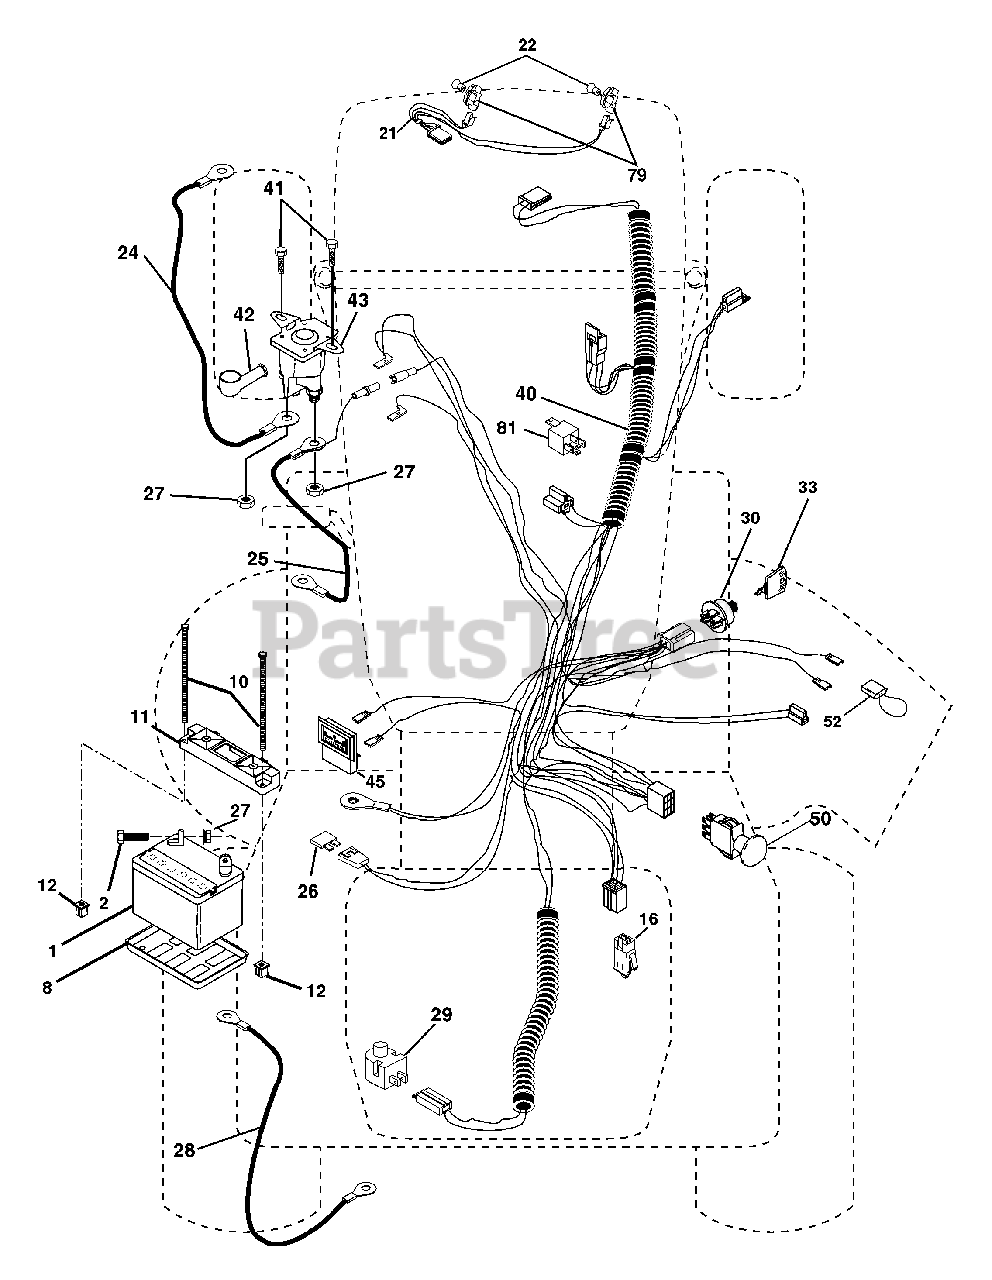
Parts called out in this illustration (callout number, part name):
1	Battery
2	Bolt Hex Head 1/4-20 x 3/4
8	Tray, Battery
10	Bolt Btr Frt 1/4-20 X 7.5 zinc
11	Holdown Battery Front Mount
12	Nut Push Nylon 1/4"
16	Switch Interlock Push-In
21	Harness Headlight
22	Bulb Light
24	Cable, Battery
25	Cable, Battery
26	Fuse
27	Nut Keps Hex 1/4-20 Unc
28	Cable, Ground
29	Switch, Plunger
30	Switch, Ign
33	Key
40	Harness, Ignition
41	Screw 1/4-20 x 1/2
42	Cover, Terminal Red
43	Solenoid
45	Ammeter
50	Switch, PTO
52	Protection Wire Loop
79	Socket, Light Bulb
81	Relay Asm.
